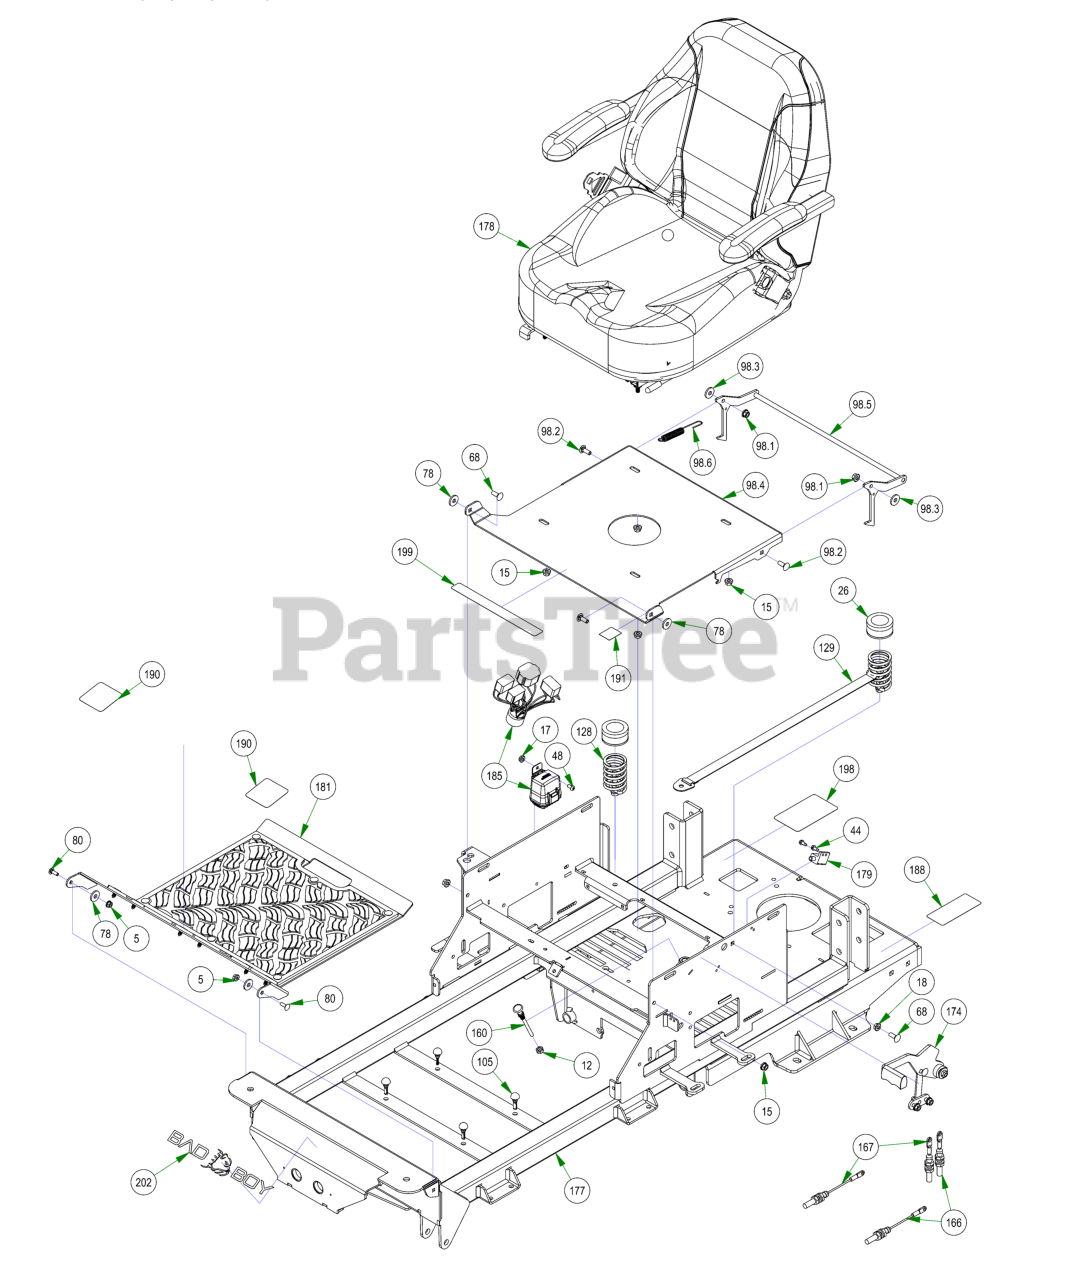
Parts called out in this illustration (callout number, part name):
5	1/4-20 NYL INSERT FLANGE LOCKNUT ZINC
12	3/8-24 HEX NUT ZINC YELLOW
15	5/16-18 NYLON INSERT FLANGE LOCKNUT ZINC
17	1/4-20 HEX SERRATED FLANGE NUT HARD/ZINC
18	5/16-18 HEX SERRATED FLANGE NUT HARD/ZINC
26	Seat Spring Cap Cover
44	12-24 X 1/2 HEX WASHER UNLSOT F TCS ZINC
48	1/4-20 X 1/2 BUTTON SOCKET CAP SCREW 18-8 STAINLESS STEEL
68	5/16-18 X 7/8 CARRIAGE BOLT ZINC
78	.360 ID X .983 OD X .120 THICK FLAT WASHER NYLON
80	1/4-20 X 3/4 CARRIAGE BOLT (GR.5) ZINC
97	2022 Maverick Rear Cover Assembly
98	MAVERICK/COMPACT OUTLAW SEAT PLATE ASSEMBLY
98.1	5/16-18 NYLON INSERT FLANGE LOCKNUT ZINC
98.2	5/16-18 X 7/8 CARRIAGE BOLT ZINC
98.3	.360 ID X .983 OD X .120 THICK FLAT WASHER NYLON
98.4	Seat Plate 2016
98.5	Seat Latch Rod Assembly
98.6	Brake Spring
105	2023 Floor Board Rubber Bumper
128	Seat Spring Assembly
129	Seat Spring Assembly
166	2021 Load Balanced Brake Cable 1
167	2021 Load Balanced Brake Cable 2
174	2021 Load Balanced Brake Handle Assembly
177	2023 Maverick Frame - Painted
178	2022 Maverick Seat
179	Safety Switch
181	2021 Maverick Floorboard Assembly
185	Wiring Harness
188	2023 EPA Build Date Punch Decal
190	2018 Maverick/2021 ZT Anti-Skid Steering Control Decals
191	2018 MZ/Magnum/ZT/MAV/Comp Out Brake Decal
198	Maverick Pump Belt Decal
199	Outlaw Warning Decal
202	Flying Bulldog Front Bumper Decal
